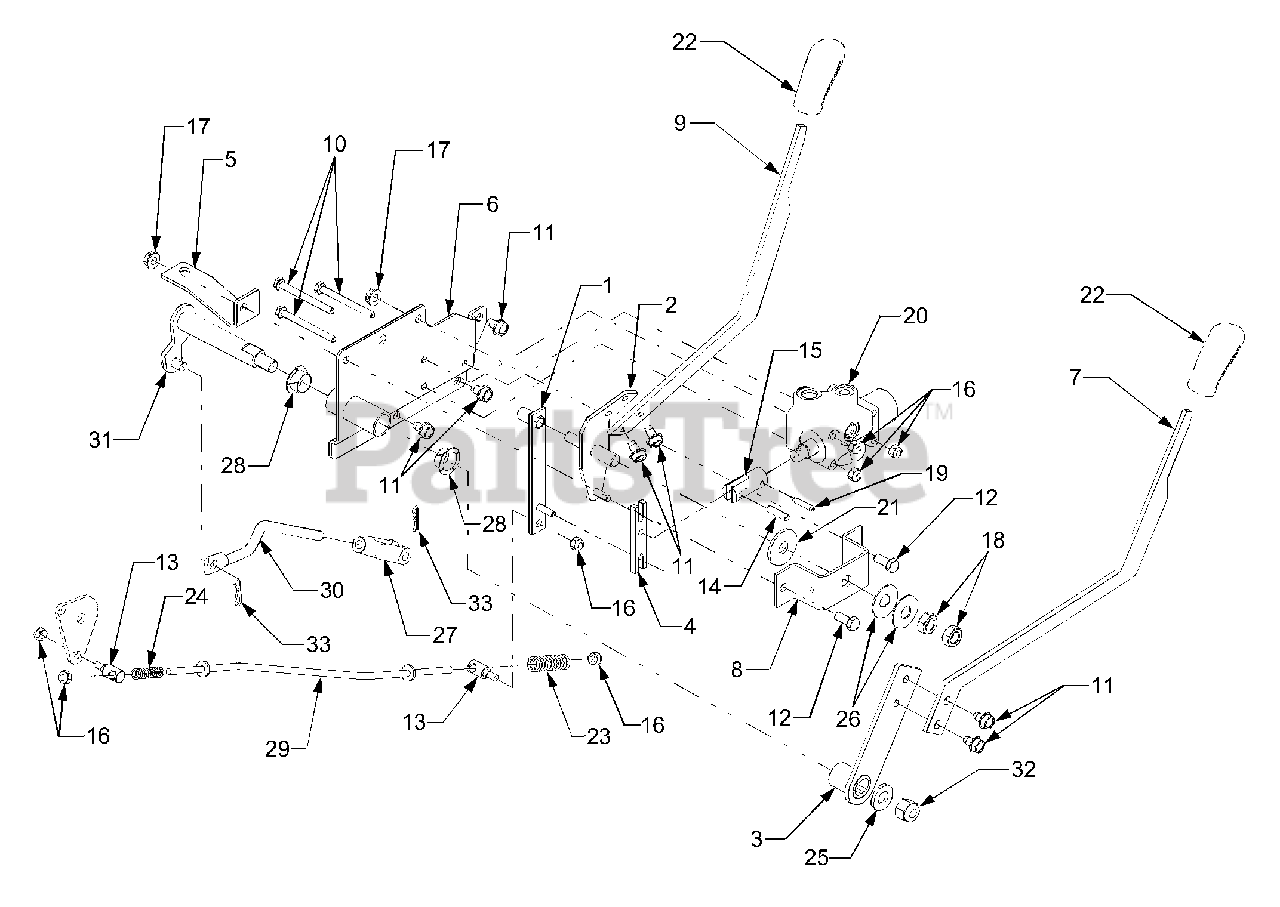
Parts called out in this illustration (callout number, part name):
1	Link Assembly, Feedback
2	Link Assembly, Input
3	Link, HI-LO Shifter
4	Link, Feedback
5	Bracket, Lift Brace
6	Bracket, Valve Mtg.
7	Handle, HI-LO Shifter
8	Bracket, Lift Mtg.
9	Handle, Lift
10	Screw, Hex Cap, 1/4-20 x 2.75 GR5
11	Screw, Hex Wash Hd. Tapp 5/16-18 x .5
12	Screw, Hex Cap, 5/16-18 x .75 GR5
13	Ferrule, Feedback Adjustment ..
14	Pin, .25 x 1.0
15	Link, Valve
16	Nut, Hex Nylon Insert Lock 14-20 GR8
17	Nut, Hex Flange Lock, 5/16-18 GR5
18	Nut, Hex Jam, 1/2-20 GR5
19	Pin, Spirol, 3/16 x 1.0
20	Valve, Hydaulic Lift
21	Washer, Friction, .515 x 1.5 x .12
22	Grip, Handle
23	Spring, Compression
24	Spring, Compression
25	Washer, Flat, .531 x 1.062 x .134
26	Washer, Belleville, .53 x 1.375 x .06
27	Clevis, Adjustment
28	Bearing, Nylon Flange .75 ID
29	Rod, Feedback
30	Rod, Hi-LO Connecting
31	Shaft, Hi-Lo Shifter
32	Nut, Hex Nylon Lock, 1/2-20
33	Pin, Internal Cotter
